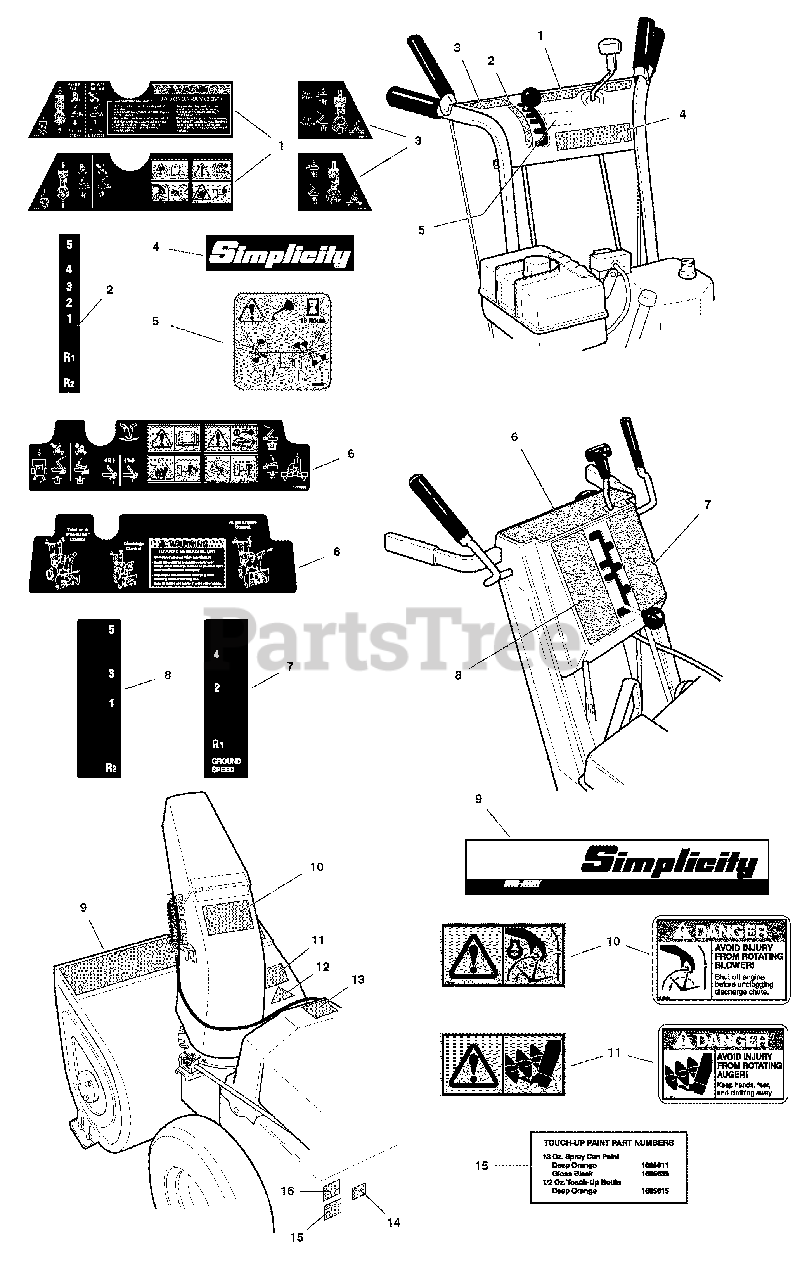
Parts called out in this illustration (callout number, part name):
1	DECAL, Dashboard EZ Turn L.H. (Tube Handle Models Only)
1	DECAL, Dashboard EZ Turn L.H.
2	DECAL, 5 4 3 2 1 R1 R2, Shift Pattern (Tube Handle Models Only)
3	DECAL, Auger Control R.H. (Tube Handle Models Only)
3	DECAL, Auger Control R.H.
4	DECAL, Simplicity (Tube Handle Models Only)
5	DECAL, Handle Lubrication (Tube Handle Models Only)
6	DECAL, Dashboard EZ Turn (Channel Handles)
6	DECAL, Dashboard EZ Turn
7	DECAL, 4 2 R1 Ground Speed, R.H. (Channel Handle Models Only)
8	DECAL, 5 3 1 R2, Shift Pattern, L.H. (Channel Handle Models Only)
9	DECAL, Stripe, 9560
9	DECAL, Stripe, 10560
9	DECAL, Stripe, 11570
9	DECAL, Stripe, 1380
9	DECAL, Stripe, 1390
10	DECAL, DANGER Chute Cleaning
10	DECAL, WARNING Chute Cleaning
11	DECAL, DANGER Avoid Injury from Auger
11	DECAL, WARNING Impeller
12	DECAL, OPEI Certified
13	DECAL, Power Boost (Channel Handle Models Only)
14	DECAL, Patent
14	LABEL, Decibel, Power MASS
15	DECAL, Touch Up Paint, Orange
16	DECAL, Serial I.D. Tag
